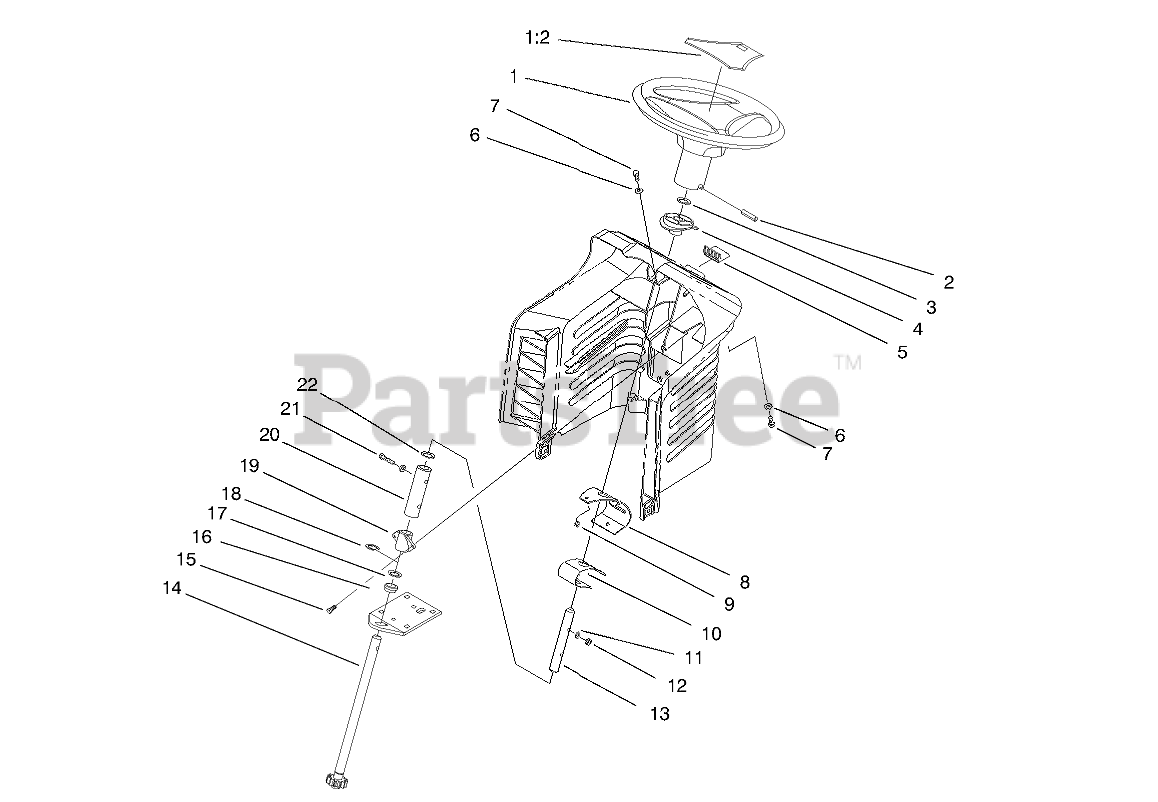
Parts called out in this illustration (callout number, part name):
1	Steering Wheel
1:2	COVER-WHEEL
2	PIN-ROLL
3	PUSH-ON RETAINING RING
4	BUSHING-SLIDING
5	RELEASE BUTTON
6	WASHER-FLAT
7	SCREW-HH
8	Bracket-Backup
9	NUT-LOCK, NI
10	SPRING LEAF
11	WASHER
12	NUT-LOCK, NI
13	UPPER STEERING SHAFT
14	SHORT STRG SHAFT WA
15	SCREW-SPECIAL
16	BEARING-FLANGE
17	WASHER-THRUST
18	E-RING
19	BUSHING STATIONARY
20	COUPLING, STEERING
21	SCREW-HH
22	WASHER-THRUST
